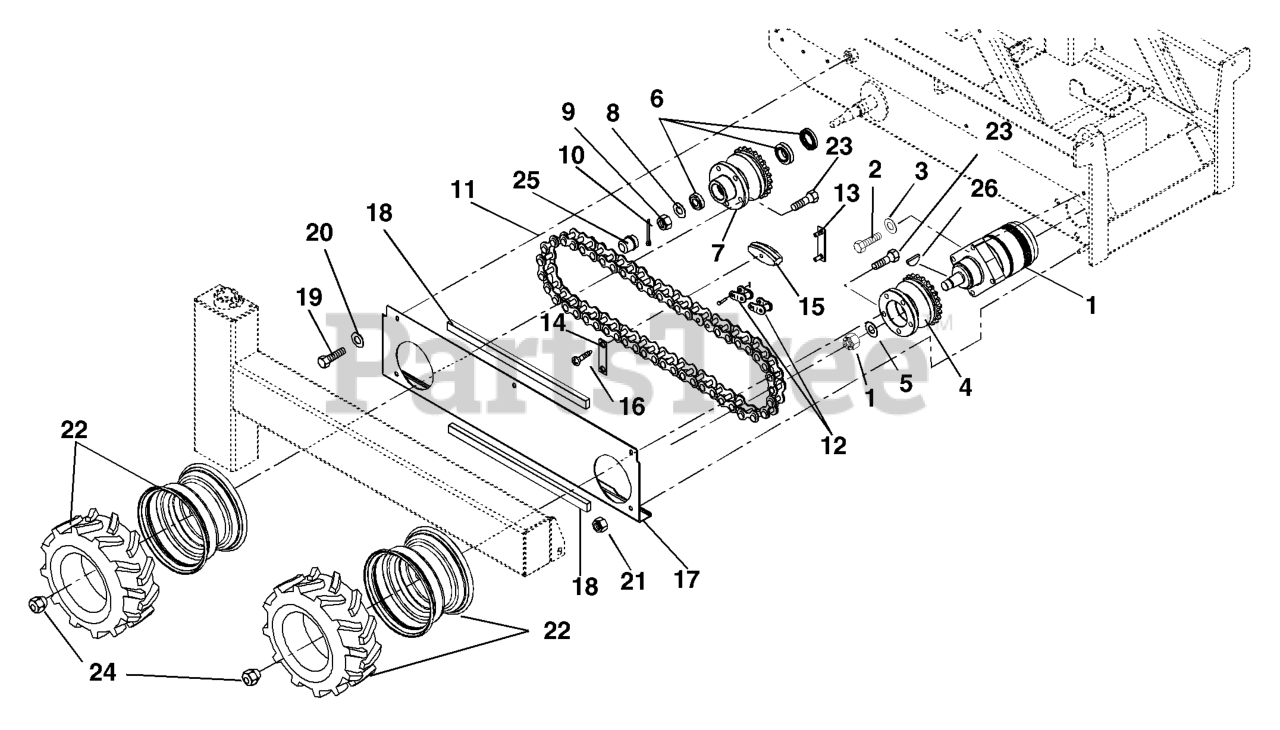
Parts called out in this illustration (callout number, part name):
1	Motor-Wheel
1	Seals, Hydraulic Motor
1	Seals, Hydraulic Motor Hi-Temp
2	Bolt-Hex M16-2 x 40 Class 10.9
3	Washer-Flat-Steel .63 x 1.005 x .062
4	Hub-Front Drive
5	Washer-Flat-Steel 1.062 x 2.0 x .134
6	Bearing-Wheel Set
7	Hub-Rear Idler
8	Washer-Hardened-Thrust .758 x 1.23 x .031
9	Nut-Slotted .75-16
10	Pin-Cotter.12 x 1.25
11	Chain-60 Roller
12	Link, Master Half
13	Bracket-Chain Tensioner
14	Bracket-Retainer Plate
15	Guide-Chain Tensioner
16	Screw-Socket Flat Head M8-1.25
17	Guard-Chain Right Hand
17	Guard-Chain Left Hand
18	Gasket-Foam with Adhesive Back
19	Bolt-Hex M8- 1.25 x 16
20	Washer-Flat-Steel .344 x .688 x .065
21	Nut-Locking-Nylon M10-1.5
22	Wheel-Lug Assembly Right Hand
22	Wheel-Lug Assembly Left Hand
22	Tire-Lug 20 x 8.00-10
22	Tube-20 x 8.00-10
23	Bolt-Wheel Lug .44-20 x 1.38
24	Nut-Lug .437-20
26	Key-Woodruff .31 x 1.00
